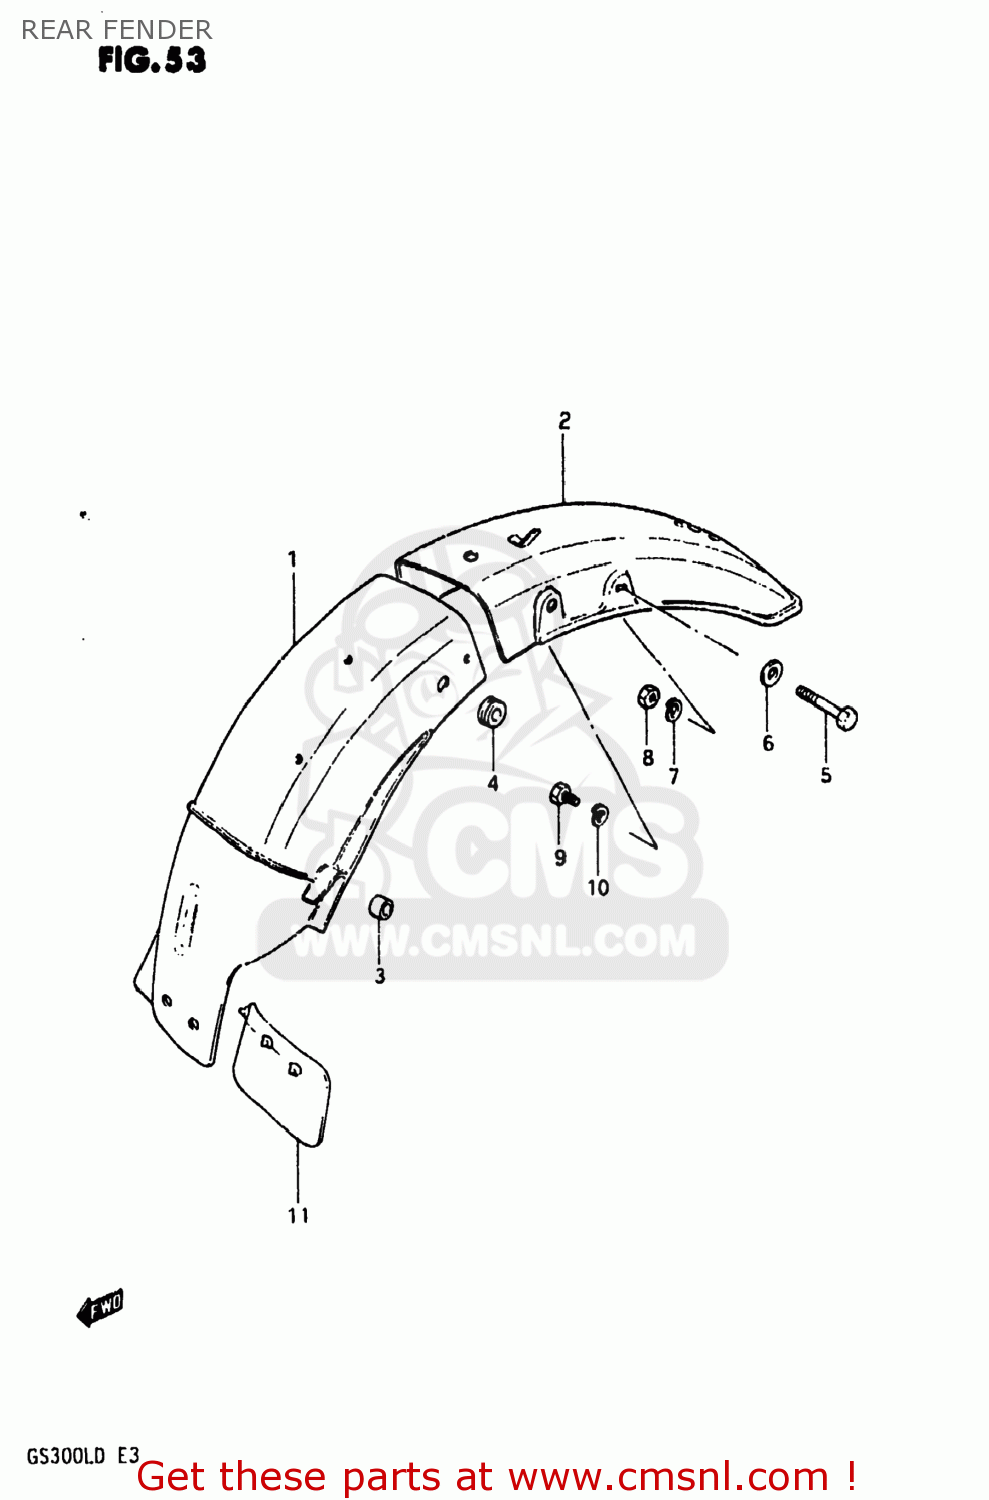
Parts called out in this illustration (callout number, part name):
1	FENDER,REAR
2	FENDER,REAR
3	CUSHION
4	CUSHION
5	BOLT
6	WASHER
7	LOCK WASHER
8	NUT
9	BOLT
10	LOCK WASHER
11	GUIDE,RR FENDER MUD
